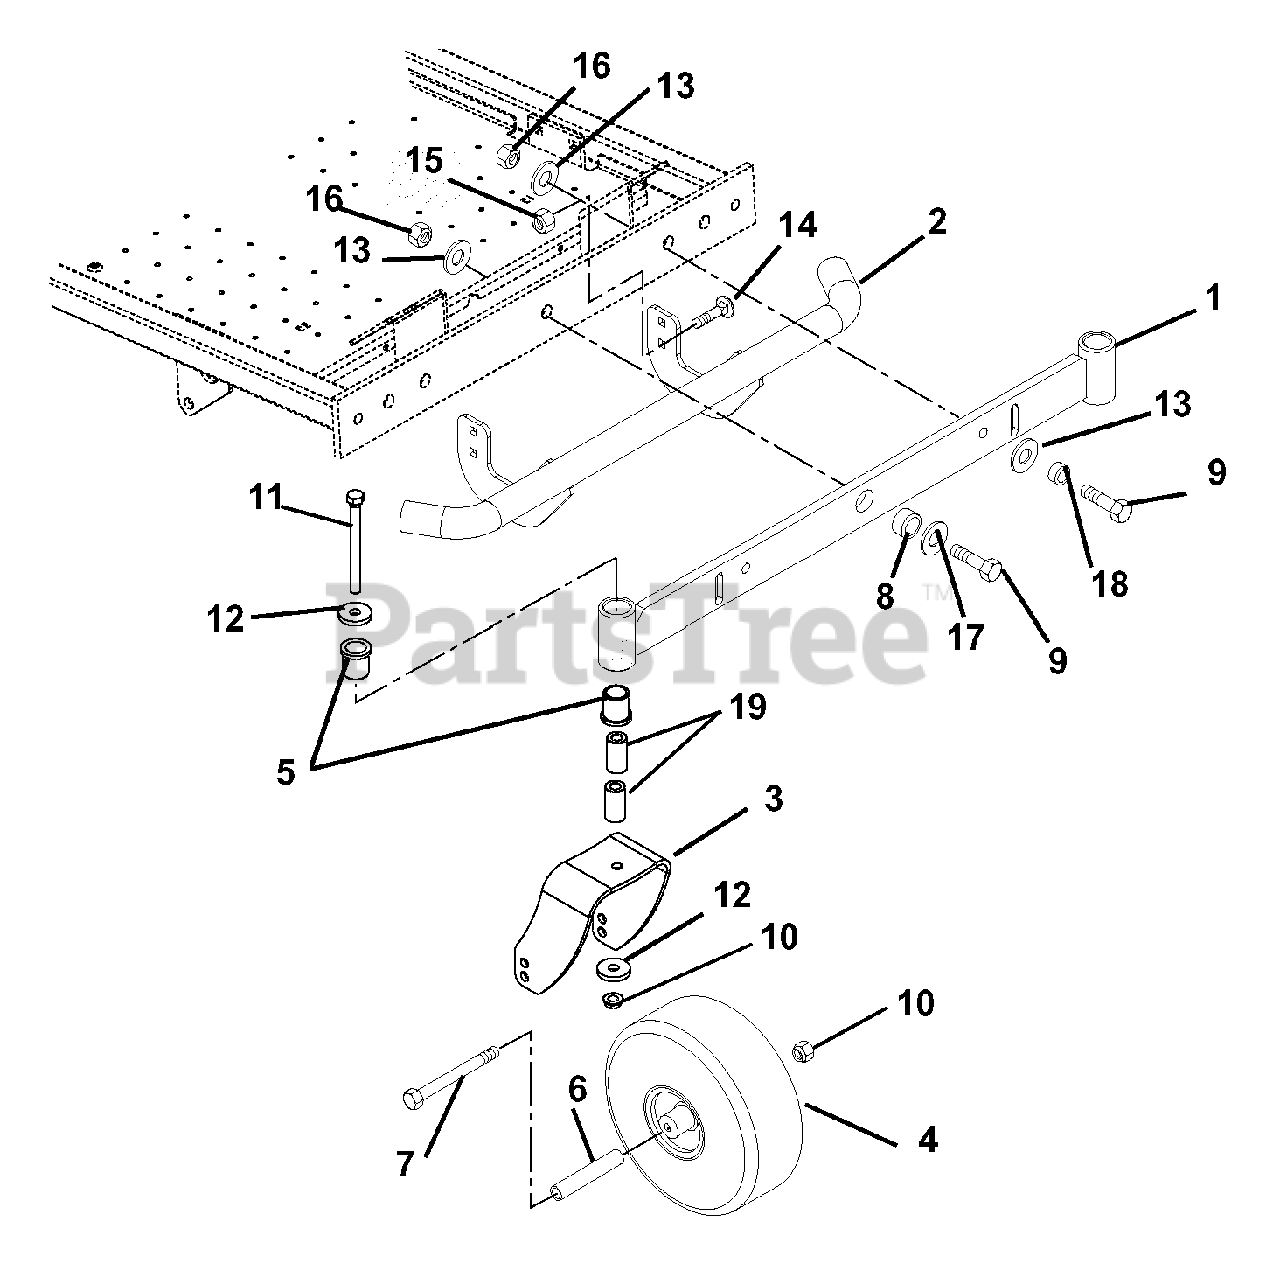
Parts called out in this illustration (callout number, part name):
1	WMT, FRONT AXLE
2	BUMPER-ZOOM
3	FORK,CASTER
4	ASSY-TIRE 4 X 11 - 4 PLY
5	BSHG-FLG 1.00X1.25X1.50X1.50EP
6	SPACER, ROLLED WHEEL
7	@BLT-HEX .50-13X6.50 GR5 YWZC
8	BUSHING, AXLE PIVOT
9	BLT-HEX .62-11X2.25 YWZC GR8
10	@NUT-LK-TOP-FLG .50-13 YWZC
11	@BLT-HEX .50-13X5.00 GR5 YWZC
12	WSHR-FL-STL.511X1.441X.125 YWZ
13	WSHR-FLT .640X1.75X.250 YWZC
14	@BLT-RDHDSQNK .38-16X1.00 G5YZ
15	@NUT-LK-NYL-FLG .38-16 YWZC
16	@NUT-LK-NYL .625-11 YWZC
17	@WSHR-FL-STL.688X1.75X.134 YWZ
18	SPACER, .750 D X .558 LONG
19	SPACER, CASTER .50X1.00X1.84
